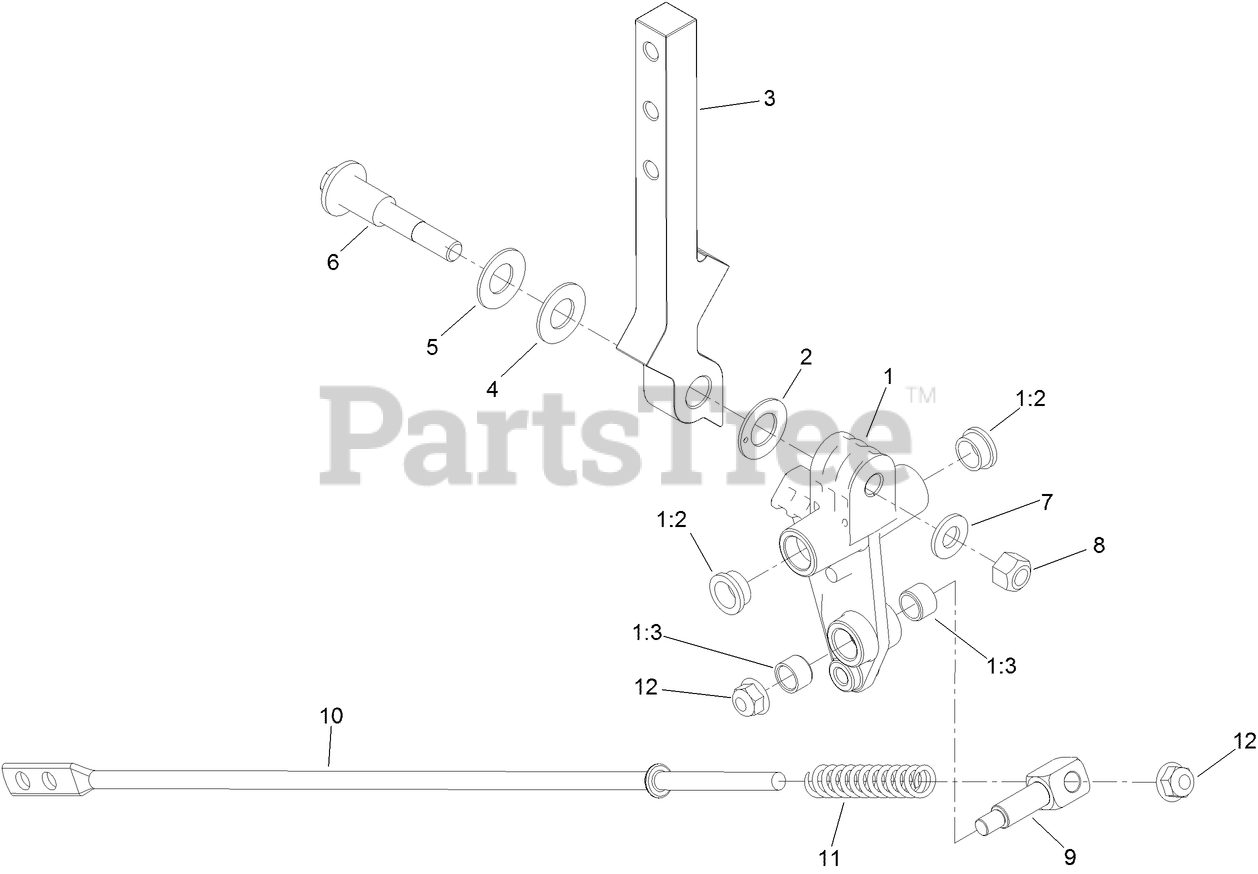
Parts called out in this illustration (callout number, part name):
1	CONTROL ARM ASM
1:2	BUSHING
1:3	BUSHING-SLEEVE
2	WASHER-FRICTION
3	ARM-CONTROL
4	WASHER
5	WASHER-BELLEVILLE
6	BOLT-PIVOT
7	WASHER-FLAT
8	NUT-LOCK, CONE
9	SWIVEL
10	LINK-CONTROL
11	SPRING-RETURN, NEUTRAL
12	NUT-HF, NI
